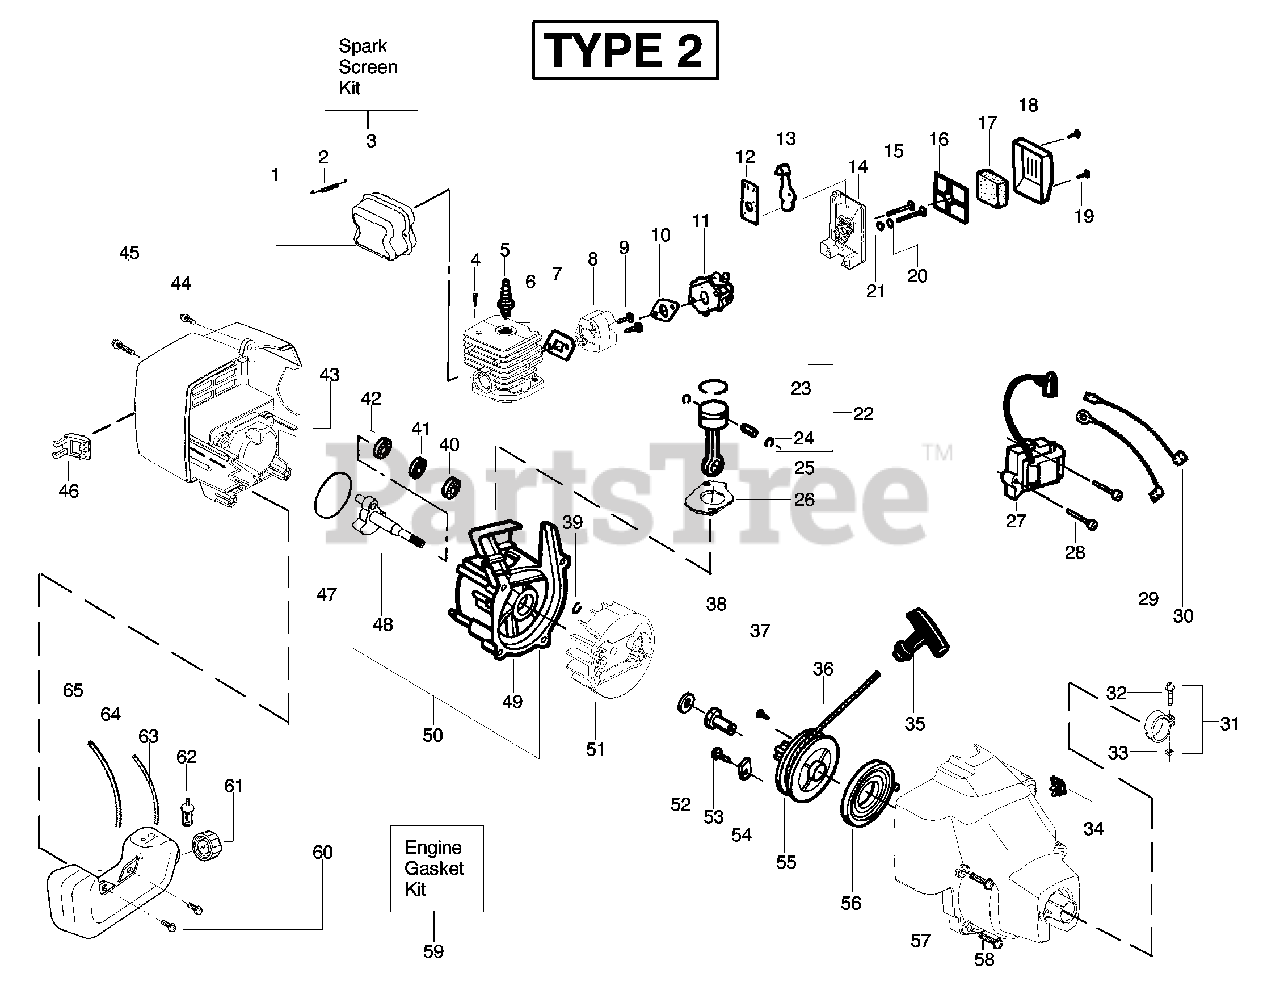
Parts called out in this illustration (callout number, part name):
1	Kit - Muffler
2	Spring-Muffler
3	Kit-Spark Arrestor
4	Screw-Cylinder
5	Spark Plug (RCJ 6Y)
6	Kit - Cylinder
7	Gasket-Cylind./Carb.
8	Adapter-Carb.
10	Gasket-Carb.
11	Kit-Carb. Walbro (WT-631)
11	Kit-Carb. Zama (C1U-W7)
12	Choke Plate Mounting
13	Shutter-Choke
16	Plate - Filter Support
17	Foam-Air Filter
18	Cover-Air Filter
20	Spacer-Choke
22	Kit - Piston
23	Piston Ring
24	Retainer-Piston Pin
25	Assy-Connecting Rod
26	Gasket-Cylinder
27	Ignition Module
29	Assy-Ground Wire
30	Assy-Leadwire
31	Assy-Nose Cone Clamp
32	Screw-Nose Cone
33	Nut-Nose Cone
34	Kit-Switch
35	Handle-Starter
36	Kit - Rope
38	Coupling-Drive
39	Retain. Ring-C'shaft
40	Outer Bearing
41	Kit-C'case Seal
42	Inner Bearing
43	Shroud-Rear
45	Screw
46	Guard-Muffler
47	O-Ring-C'case/Shrd
48	Assy-Crankshaft
49	Assy-Crankcase
50	Assy-C'case & C'shaft
51	Assy-Flywheel
52	Washer-Flat
54	Retainer-Can
55	Kit-Starter Pulley
56	Spring-Starter
57	Assy.-Fan Hsg
58	Screw
59	Kit-Engine Gasket
61	Assy-Fuel Cap
62	Assy-Fuel Pickup
63	Kit-Fuel Line (Small)
64	Kit-Fuel Line (Large)
65	Assy-Fuel Tank
